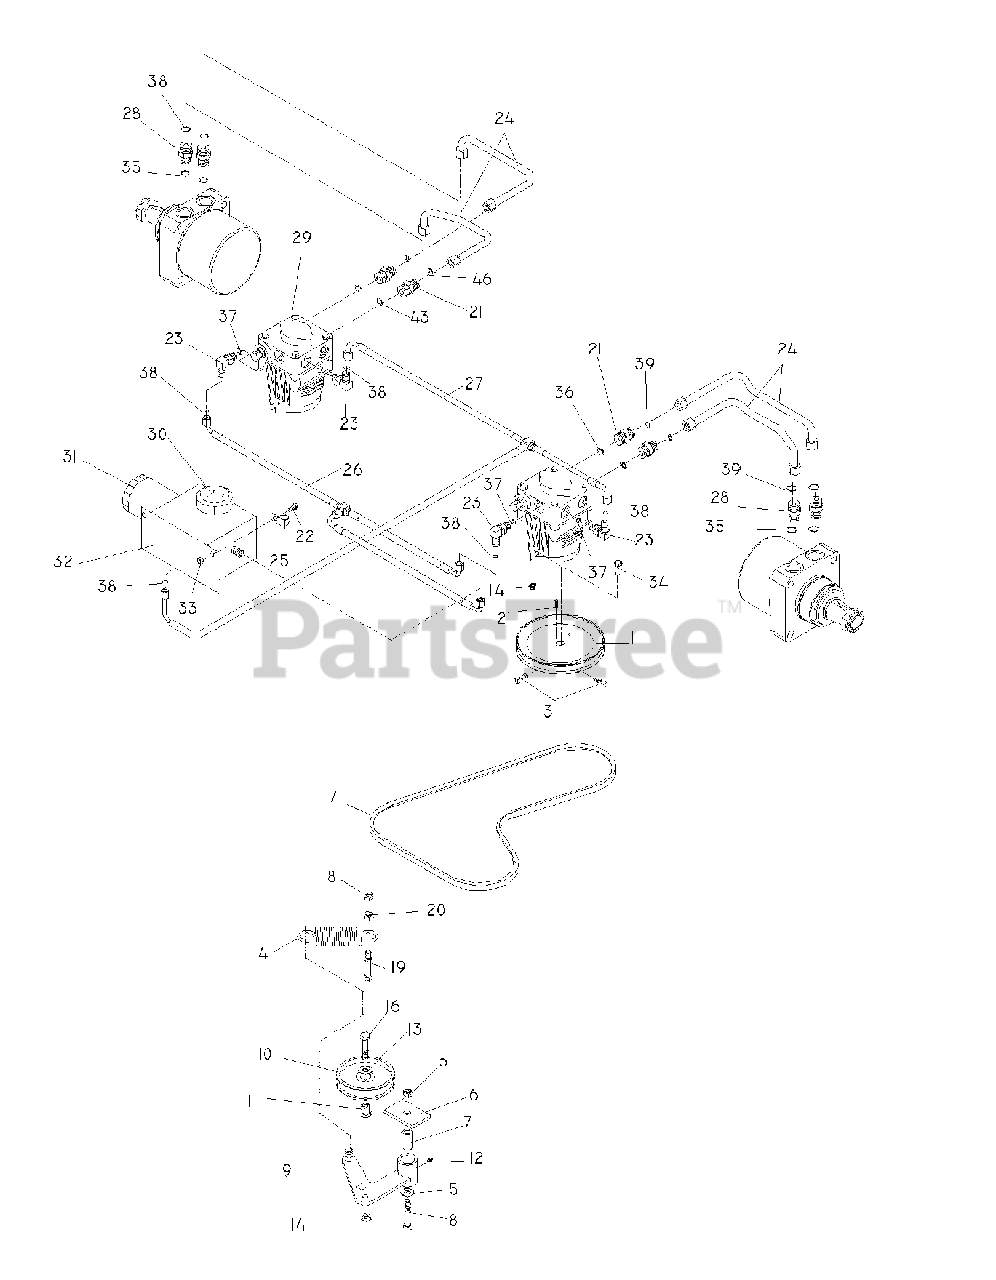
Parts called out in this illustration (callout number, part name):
2	KEY 5 MM SQ X 25 MM
3	SCREW 5/16C X 5/8 SQ HEAD
5	NUT 1/2-13 HEX NYLOC ZD
7	PIVOT BUSHING
8	HCS 1/2C X 3 1/4
9	IDLER ARM WLDT
10	IDLER PULLEY
11	BUSHING, IDLER FLANGE
12	ZERK
13	WASHER 3/8 FLAT
14	NUT 3/8C CENTERBLOCK
15	WASHER 1/2 FLAT
16	HCS 3/8-16 X 1 3/4 GR5
17	PUMP BELT
18	NUT 3/8-16 NYLOC
19	HCS 3/8C X 2
20	NUT 3/8C WHIZ
21	FITTING, STRAIGHT F6400-8-8-0
22	HCS 5/16C X 3/4
23	ELBOW, F6801-6-6-0 90 DEGREE
24	HYDRAULIC HOSE
25	LOOM CLIP
26	T-ASSEMBLY
27	T-ASSEMBLY
28	FITTING
29	HG_PUMP, 10CC W/O FAN
30	HYDRAULIC CAP
31	HYDRAULIC OIL FILTER
32	RESERVOIR W/CAP & FILTER
33	NUT 5/16 NYLOC
34	HCS 3/8C X 1 SERRATED HEAD
